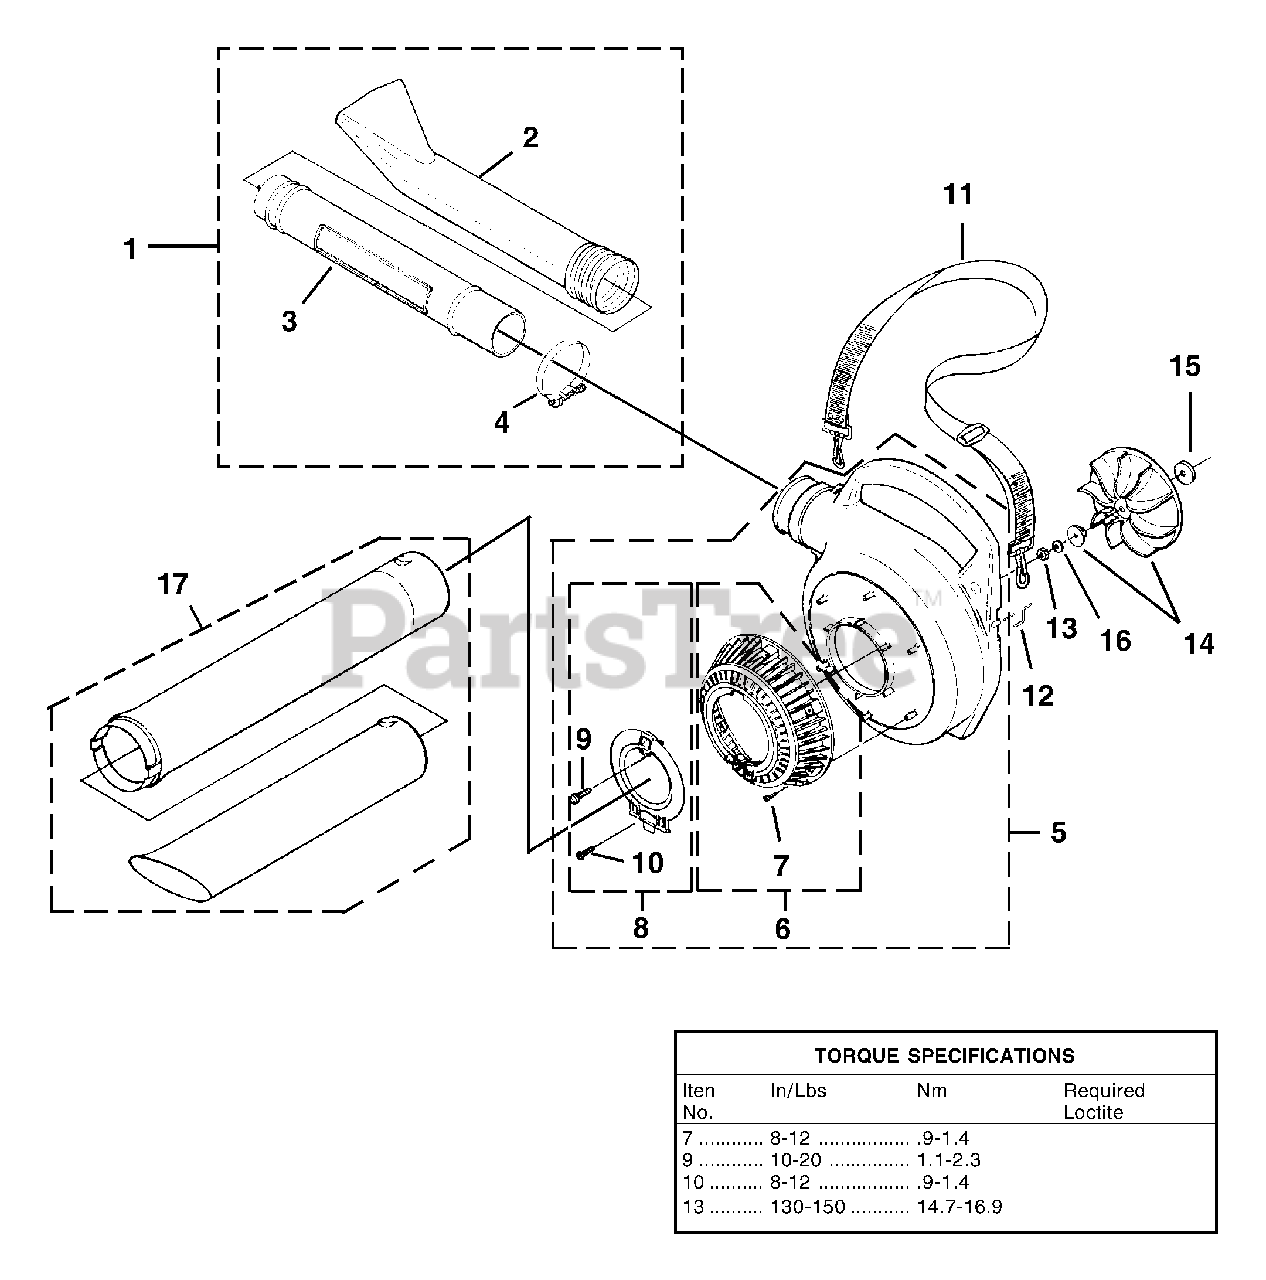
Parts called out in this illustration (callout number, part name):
1	BLOWER TUBE KIT
2	NOZZLE-Sweeper
4	CLAMP w/Fasteners
5	VOLUTE HOUSING KIT
6	BLOWER VAC GRILLE KIT
7	SCREW-Thread Form. (#6 X 3/8")
8	ACCESS DOOR KIT
9	SCREW-Thread Rolling (#10 X 5/8")
10	SCREW-Thread Form. (#8 X 1/2")
11	SHOULDER STRAP
12	WIRE LOOP
13	NUT-Hex (3/8-24)
14	BLOWER FAN KIT
15	WASHER-Flat
16	WASHER-Bellville (3/8")
17	VACUUM TUBE KIT
